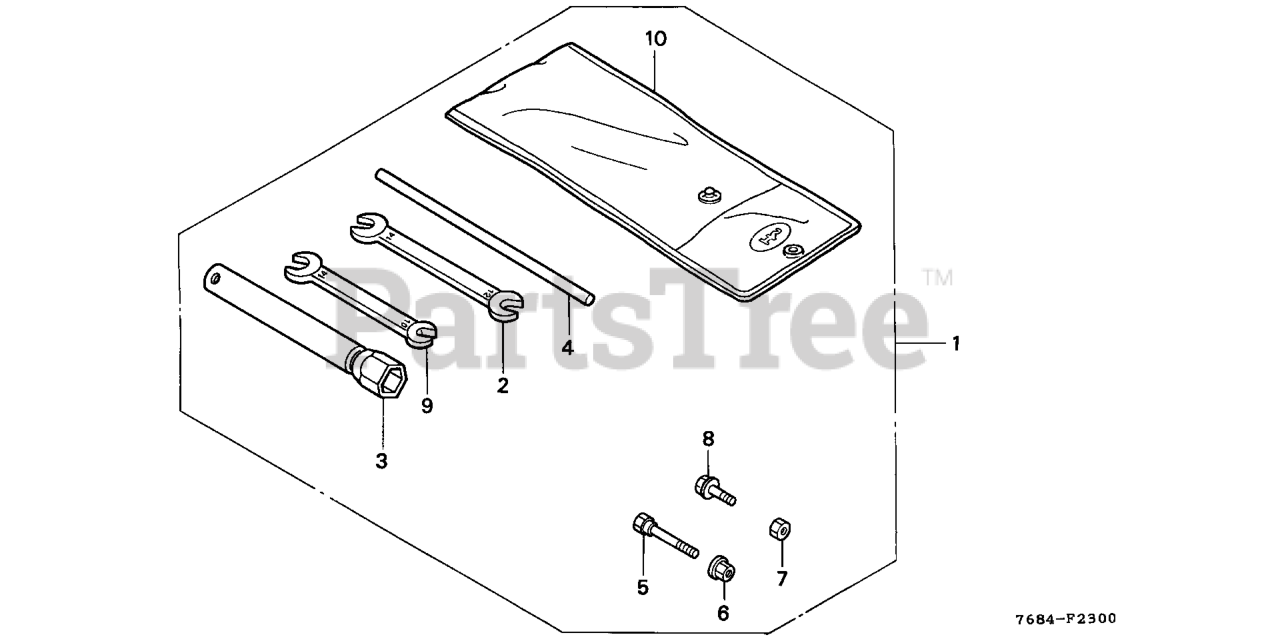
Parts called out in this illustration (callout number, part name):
1	TOOL KIT
1	TOOL KIT (NOT AVAILABLE)
2	SPANNER (12X14)
3	WRENCH, SPARK PLUG (NOT AVAILABLE)
4	HANDLE, BOX WRENCH (NOT AVAILABLE)
5	BOLT, LOCK
6	NUT, SELF-LOCK (6MM)
7	NUT, HEX. (6MM)
8	BOLT, FLANGE (6X16) Use from Engine SN 2056820.
8	BOLT, HEX. (6X16)
9	WRENCH (10X14) (OPEN END)
10	BAG, TOOL
